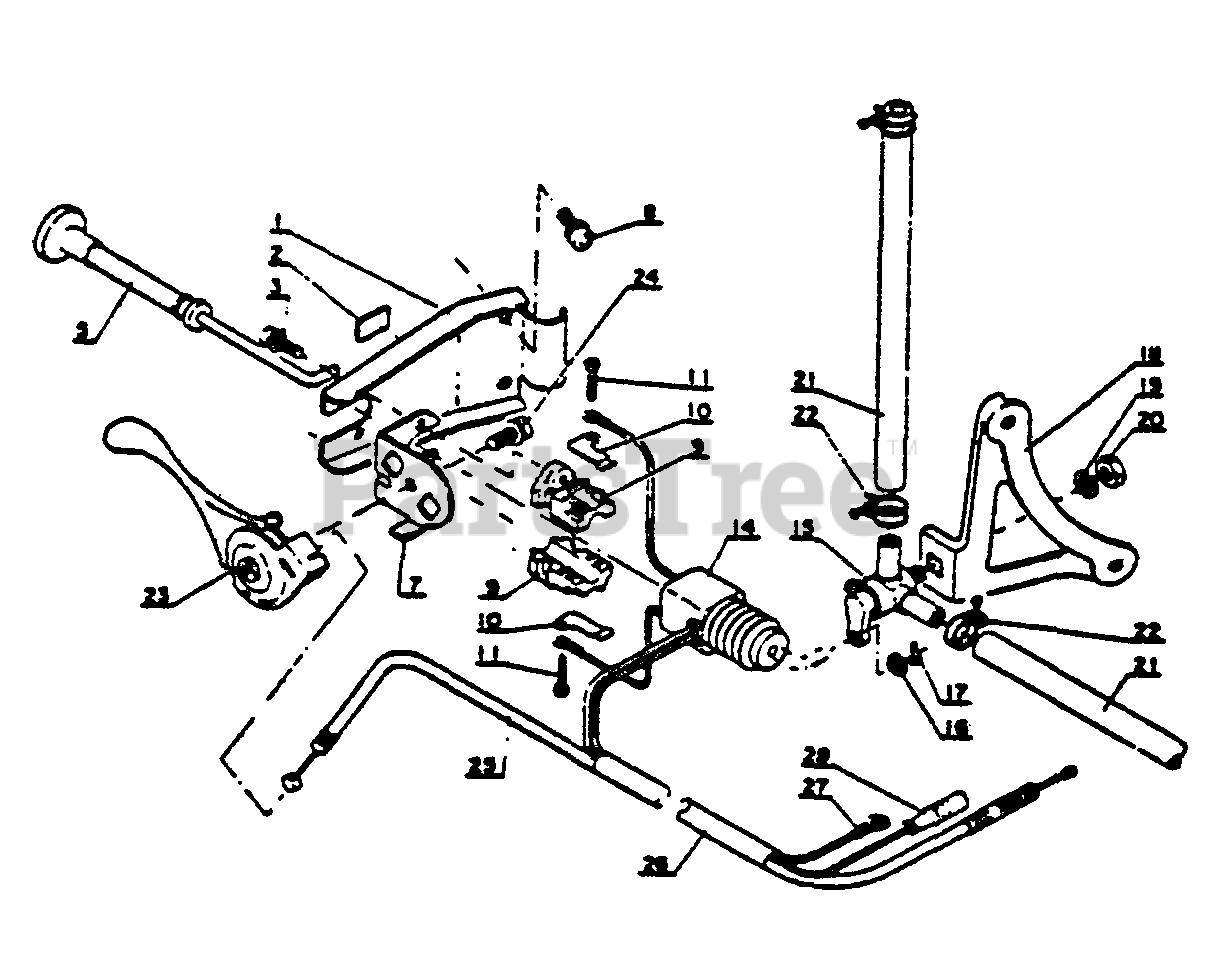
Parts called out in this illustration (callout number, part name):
1	BRACKET, SWITCH
2	LABEL - STOP
3	SCREW - 4X12
5	KNOB
7	BRACKET, THROTTLE LEVER
8	SCREW - 5X10
9	BODY, SWITCH
10	CONTACT, SWITCH
11	SCREW - 3X15
14	BRACKET, SWITCH
15	FUEL VALVE ASSY
16	WASHER - 4
18	BRACKET, FUEL VALVE
19	LOCKWASHER - 6
21	PIPE - FUEL
22	RETAINER, PIPE
23	LEVER, THROTTLE
24	SCREW - 5X12
25	THROTTLE CONTROL ASSY
26	THROTTLE CONTROL ASSY
27	LEAD - GROUND
28	LEAD - IGNITION
